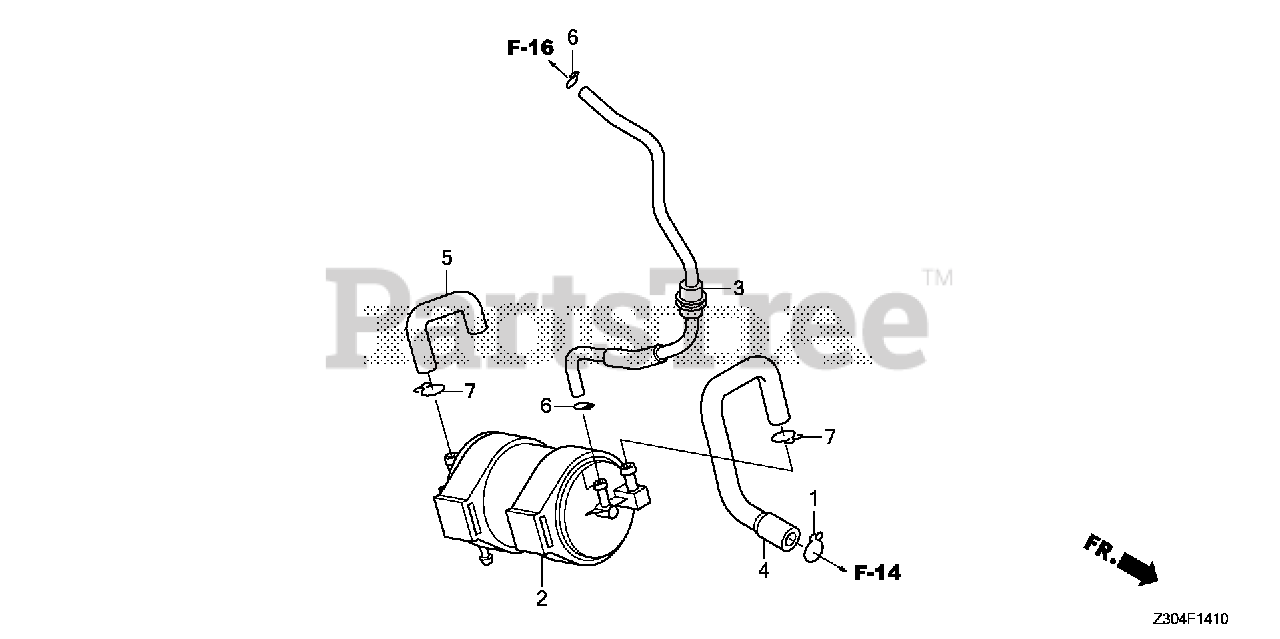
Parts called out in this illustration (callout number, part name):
1	CLIP, BREATHER TUBE
2	CANISTER ASSY.
3	TUBE CANISTER CHARGE
4	TUBE, CANISTER PURGE
5	TUBE, CANISTER AIR
6	CLIP, TUBE (B8)
7	CLIP, TUBE (B12)
